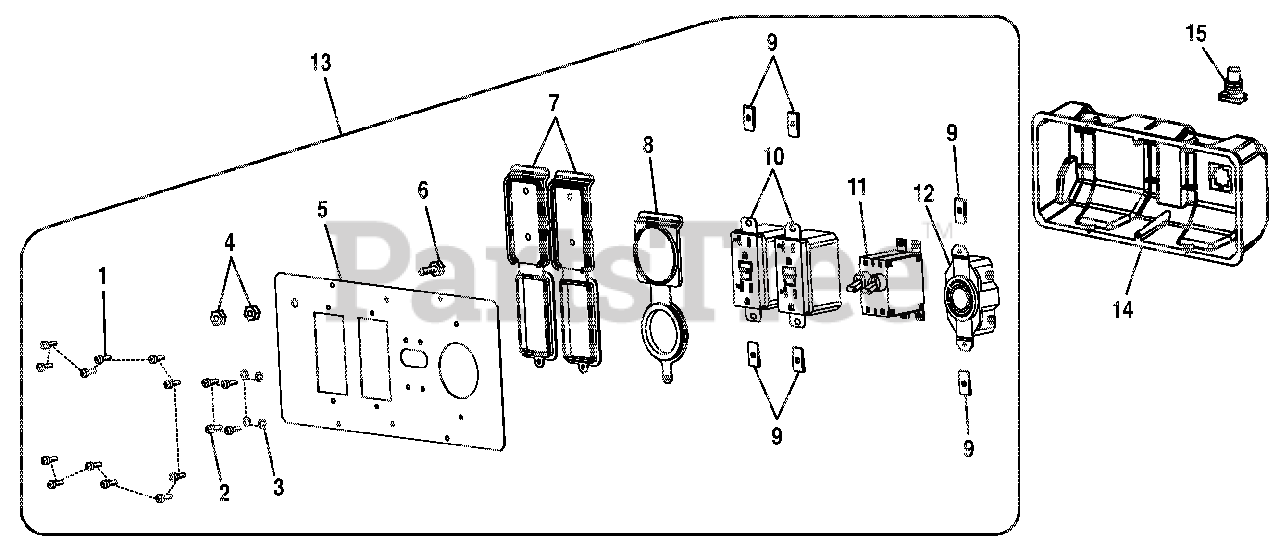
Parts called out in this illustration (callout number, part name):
1	SCREW (6-20 X 3/8 IN.)
2	SCREW (M3 X 6)
3	LOCK WASHER
4	HEX NUT (1/4-20)
5	COVER PLATE
6	SCREW (1/4-20 X 5/8 IN HEX HD)
7	OUTLET COVER (120 VOLT)
8	OUTLET COVER (240 VOLT)
10	DUPLEX RECEPTACLE (120 VOLT)
11	CIRCUIT BREAKER(20AMP 125VOLT)
12	TWST LCK RECEPT 120/240VLT 20A
13	FRONT PANEL
14	REAR CONTROL PANEL
15	RUBBER BOOT
